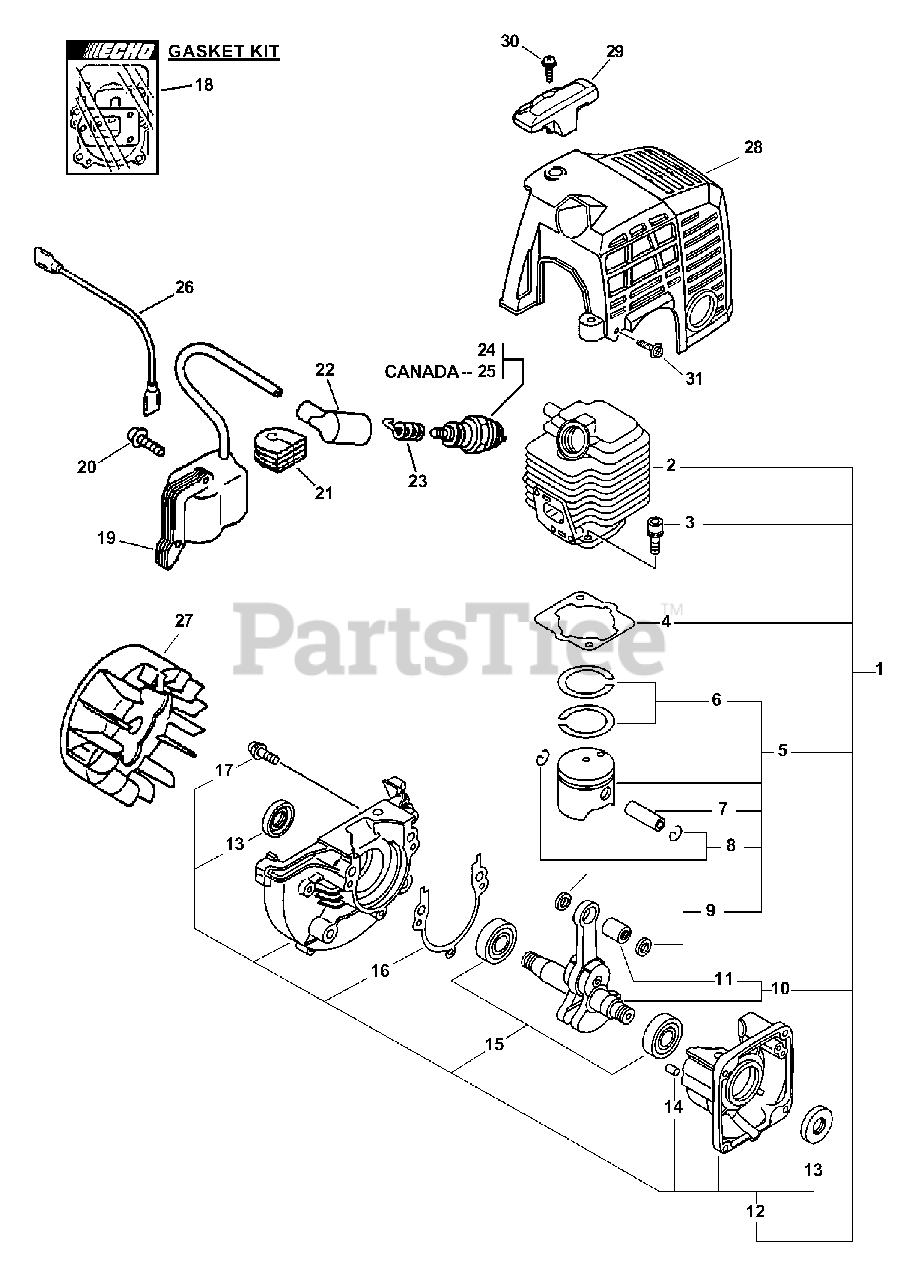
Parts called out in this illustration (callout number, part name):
1	SHORT BLOCK -- SB1027
2	CYLINDER
3	SCREW - 5X22
4	GASKET, CYLINDER
5	PISTON KIT
6	RING, PISTON
7	PIN, PISTON
8	RING, RETAINING
9	SPACER, PISTON
10	CRANKSHAFT ASSY
11	BEARING, NEEDLE
12	CRANKCASE KIT
13	SEAL, OIL
14	PIN - LOCATING
15	BEARING, BALL - 6201
16	GASKET, CRANKCASE
17	SCREW - 5X28
18	GASKET KIT
19	COIL, IGNITION
20	SCREW - 4X22
22	CAP, SPARK PLUG
23	TERMINAL, SPARK PLUG CAP
24	SPARK PLUG -- BPM-7Y
25	SPARK PLUG -- RCJ-7Y
26	LEAD - IGNITION
27	FLYWHEEL
28	COVER, ENGINE
29	GUARD - TOP
30	SCREW - 5X16
31	SCREW - 4X16
